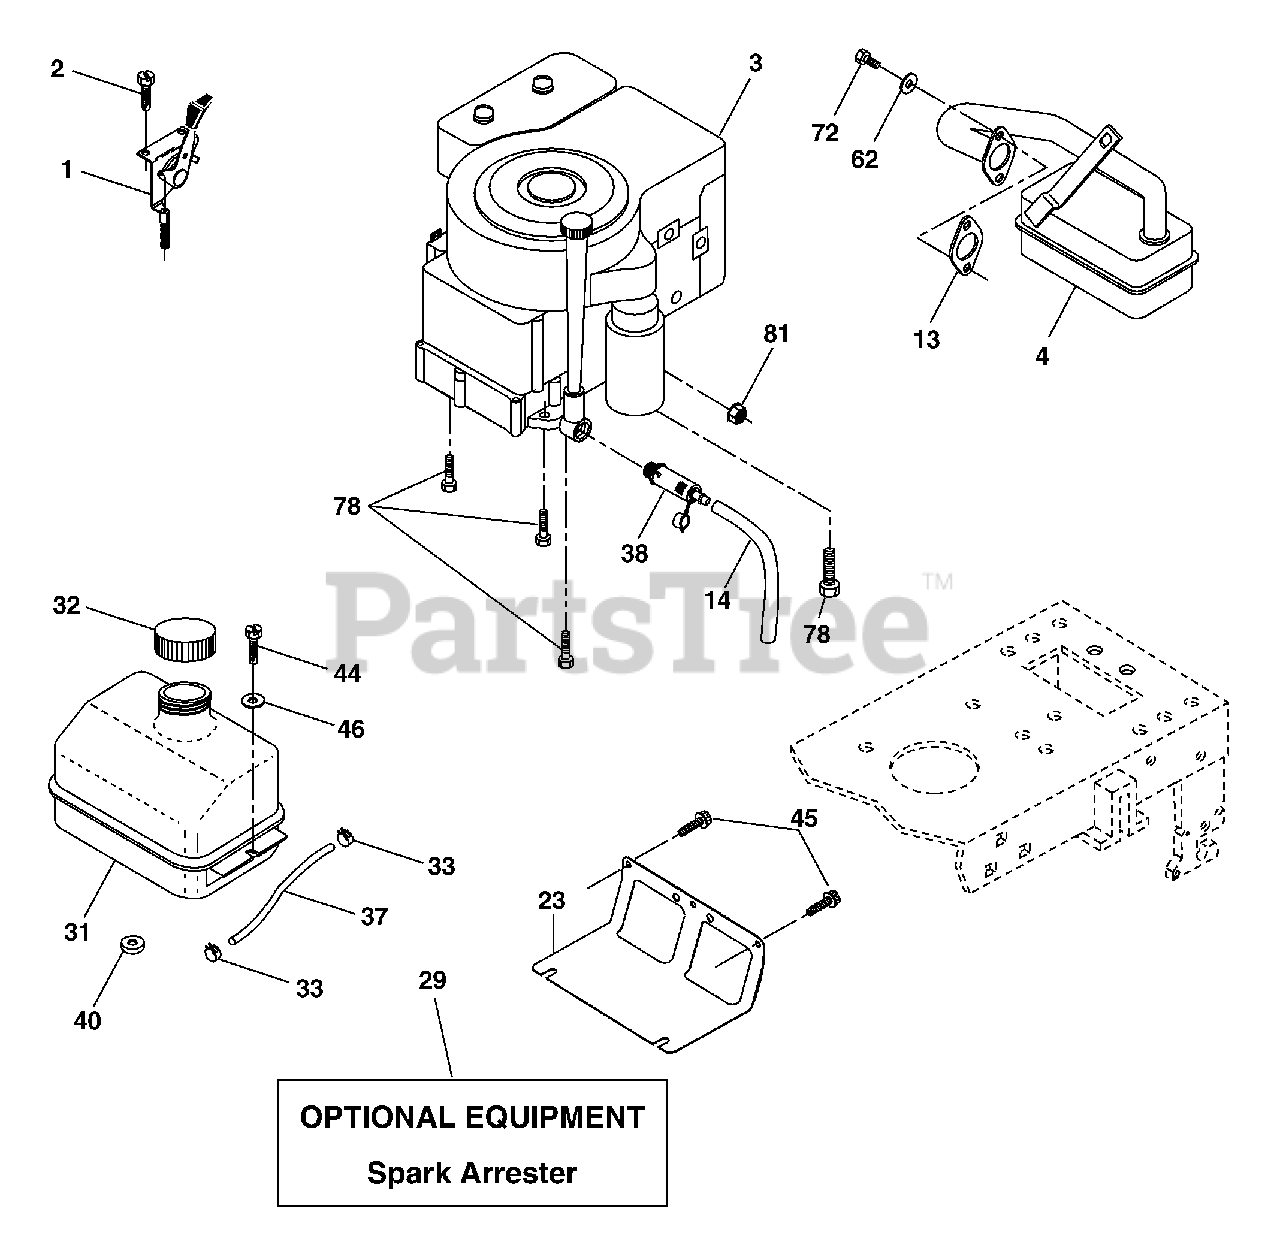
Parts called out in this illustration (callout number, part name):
1	Control, Throttle/Choke
2	Screw Hex Thd Cut 1/4-20 x 1/2
13	Muffler Gasket
14	Tube Oil Drain
23	Shield, Browning/Debris Guard
29	Arrester, Spark
31	Tank, Fuel
32	Cap, Fuel
33	Clamp, Hose Blk
37	Line, Fuel
38	Plug Drain Oil Easy
40	Bushing Snap
44	Screw 1/4-20 x 3/4
45	Screw Hex Wsh Thdrol 3/8-16 x 3/4
46	Washer 9/32 x 7/8 x 16 Ga.
62	Washer Split
72	Screw Socket Head 5/16-18 x .75
78	Screw 3/8-16 x 1-1/4
81	Nut Keps Hex 1/4-20 unc
